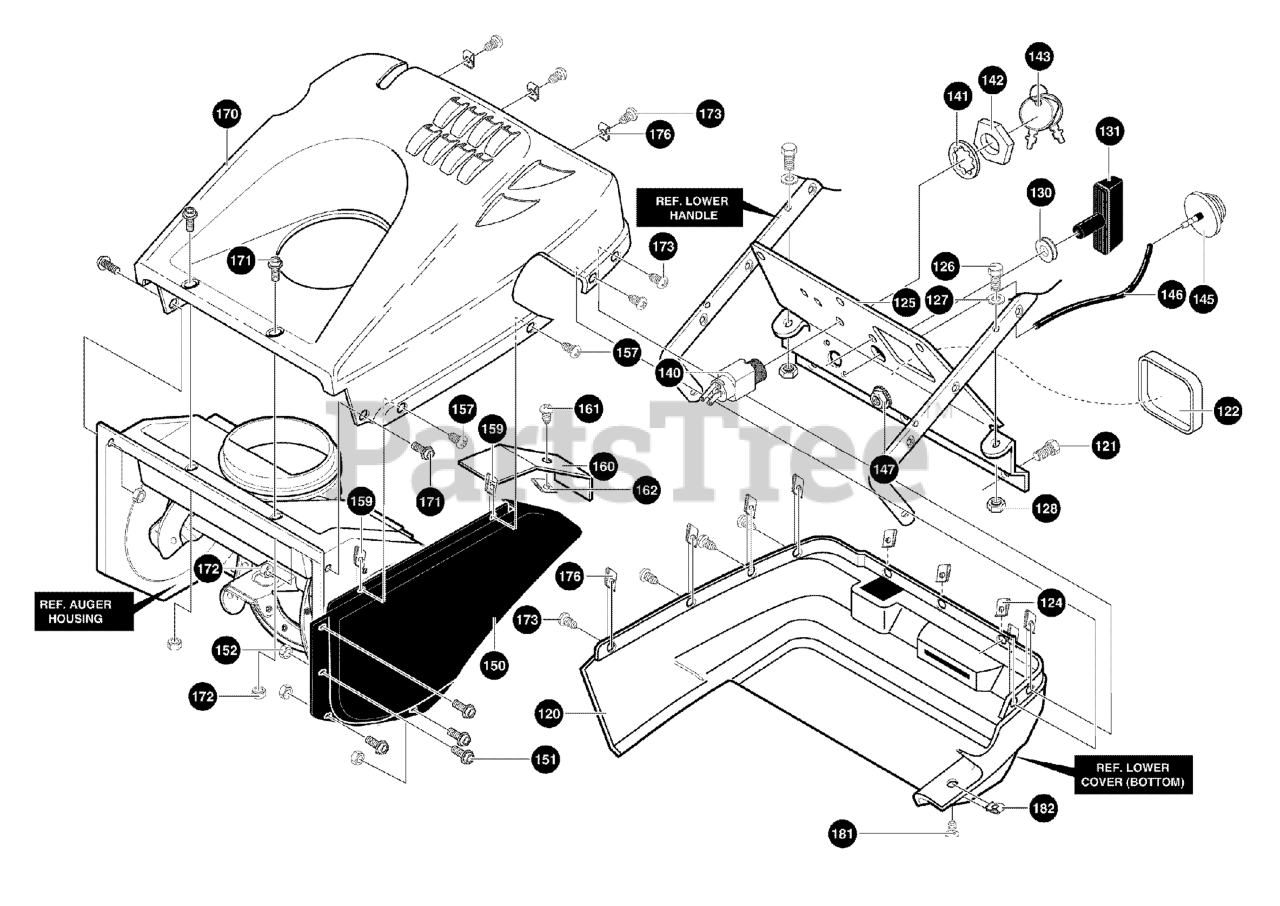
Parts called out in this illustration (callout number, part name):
120	COVER, BOTTOM
121	SCREW, 1/4-14X.75
122	PANEL, SPARK ACCESS
124	NUT, 1/4-10 SPEED J TYPE
125	CONTROL PANEL
126	SCREW, 1/4-20X1.25
127	FLATWASHER
128	NUT, 1/4-20
130	GOMMET & WASHER
131	KNOB T
140	SWITCH, IGNIT.
141	WASHER
142	NUT. 5/8-32
143	KEYS & RING
145	PRIMER, BULB
146	HOSE PRIM 9.50LG
147	NUT, 1/4-20
150	COVER, BELT
151	SCREW, 10-24X.50
152	NUT, #10-24
157	SCREW, 1/4-14X.75
159	NUT, 1/4-10 SPEED J TYPE
160	SHIELD, HEAT
170	COVER, TOP
171	SCREW,#10-24X.50
172	NUT #10-24
173	SCREW, 1/4-14X.75
176	NUT, 1/4-10 SPEED J TYPE
181	SCREW, 1/4-14X.75
182	NUT 1/4-10 SPEED J TYPE
